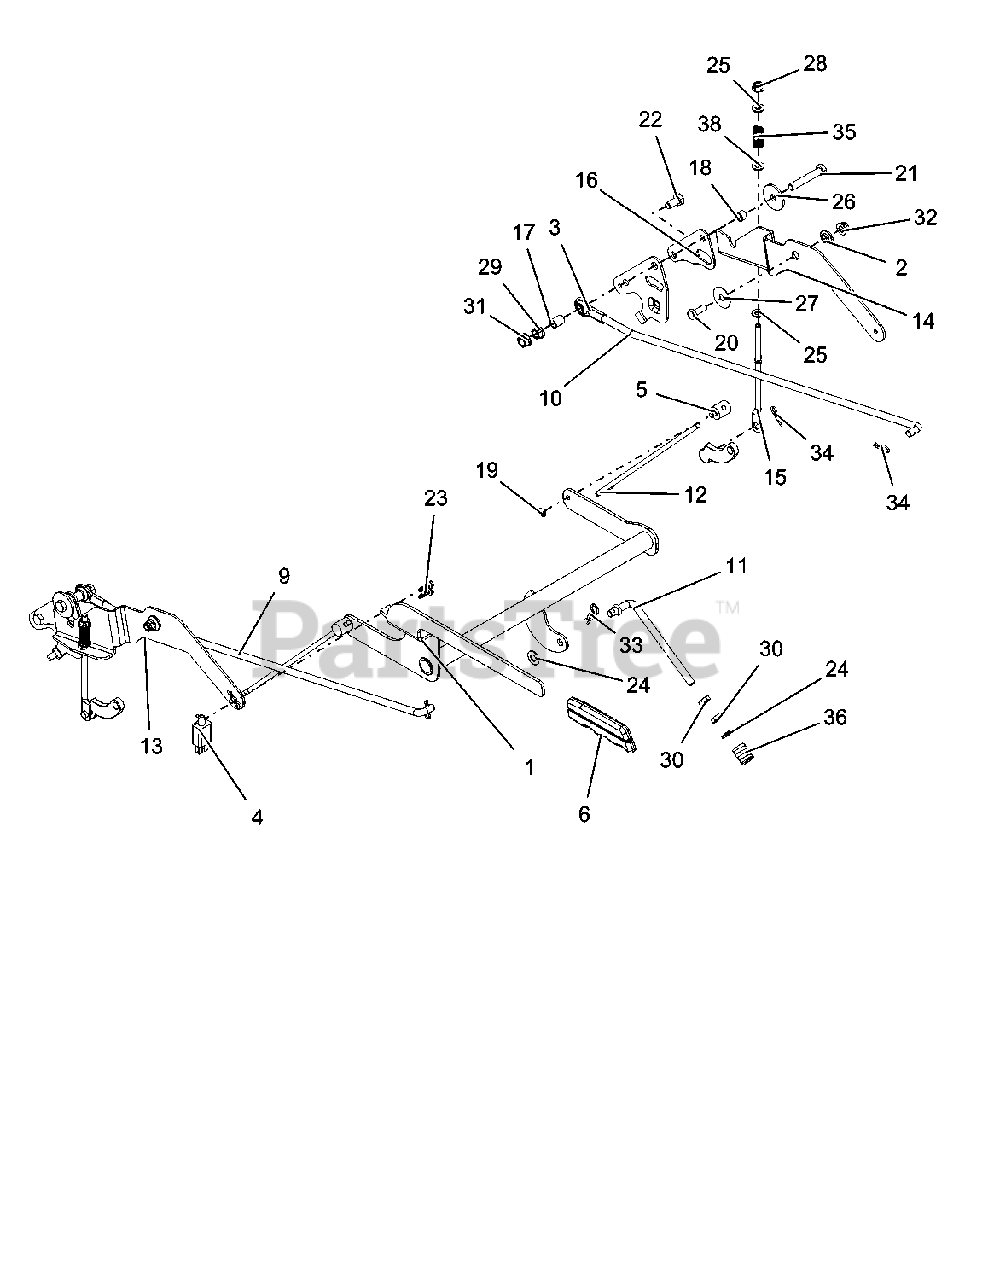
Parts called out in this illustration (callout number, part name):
1	WLDMT, BRAKE LEVER
2	BSHG, FLG .325X.499X.26X.88
3	ROD END, .38 RH
4	SWITCH- DOUBLE POLE N.O./N.O.
5	TRUNION, 1/4-20
6	GRIP, PARKING BRAKE (YELLOW)
9	STEERING, LINKAGE RH
10	STEERING, LINKAGE LH
11	LINK, OVER CENTER, PARKING BRK
12	LINK, BRAKE ARM
13	INTERLOCK, RH BRAKE LINK
14	INTERLOCK, LH BRAKE LINK
15	LINK, BRAKE COG
16	PLATE, TRANSAXLE ADAPTOR
17	SPCR, SLV .385X.500X.652
18	SPCR, SLV .385X.500X.350
19	E-RING, .250 X .025
20	BOLT-HEX.31-18X.875 YWZC GR5
21	@BLT-HEX .38-16X2.25 GR5 YWZC
22	@BLT-HEX .38-16X.75 GR5 YWZC
23	SCR-TAP #12X.75 BOSS INDHXHD
24	@WSHR-FL-STL.406X.812X.065 YWZ
25	@WSHR-FL-STL.344X.688X.065YWZC
26	WSHR-FL-STL .380X1.50X.125YWZC
27	WSHR-FL-STL .347X1.254X.048YWZ
28	@NUT-LK-CTR-FLG .31-18 YZ GR F
29	NUT-LK-CTR-FLG .38-16 YWZC
30	NUT-HEX-JAM .375-16 YWZC
31	@NUT-LK-TOP-FLG .38-16 YWZC
32	@NUT-LK-NYL-FLG .31-18 YWZC
33	PIN-HAIR CTR .09 X 1.50 YWZC
34	PIN-HAIR INT .08X.18X1.18 YWZC
35	SPRING, COMPRESSION
36	SG-COMP .187X.56X1.62
38	@WSHR-FL-STL.344X.688X.065YWZC
